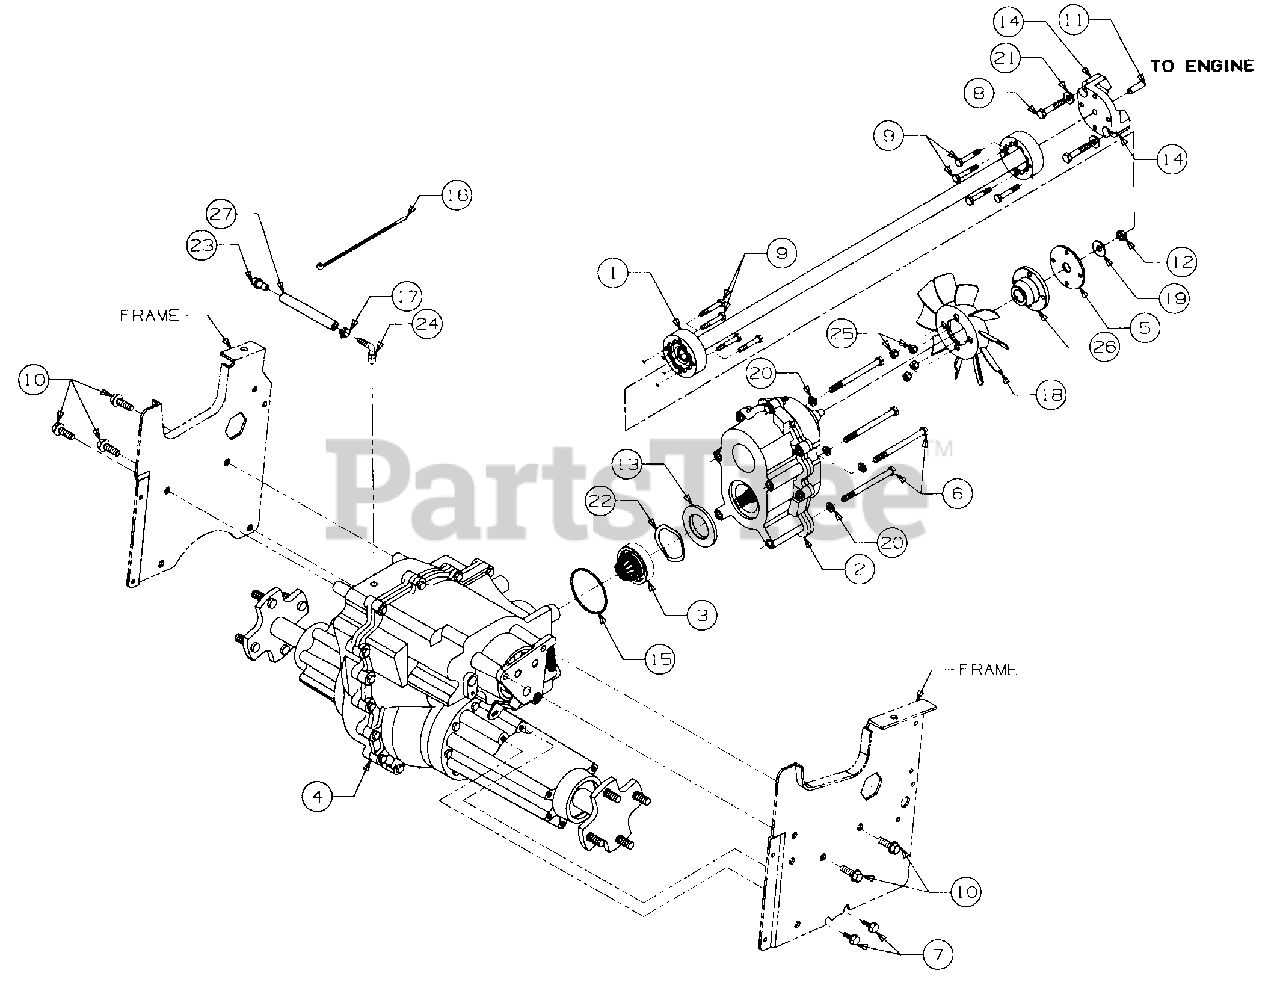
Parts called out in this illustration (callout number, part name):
1	Shaft Assy, Drive, 29.06 Lg
2	Clutch Assy
3	Pinion Assy, Input
4	Transmission Assy, 6-Speed
5	Plate, Drive Shaft Spacer
6	Screw, Hex Cap, 5/16-18 x 4.0 Lg GR5
7	Screw, Hex Wash Sf-Tapp 5/16-18 x .75 Lg
8	Screw, Hex Cap, 5/16-18 x .75 Lg GR5
9	Bolt, Hex Patch, 1/4-20 x 1.62 Lg GR5
10	Screw, Hex Wash Tapp 3/8-16 x 1.25 Lg
11	Pin, Locating
12	Nut, Hex Center Lock Jam, 3/8-24
13	Plate, Clutch Output Shim
14	Adapter, Drive Shaft
15	O-Ring, 2.75 x .103
16	Tie, Self-Clinch Cable
17	Clamp, Hose
18	Fan, 10 Blade Cooling
19	Washer, Bell, .380 x .88 x .062 Thk
20	Washer, Lock, 5/16
21	Washer, Flat, .312 x .750 x .119 Thk
22	Washer, Spring Wave, 1.96 x 2.44 x .06 Thk
24	Fitting, Elbow
25	Nut, Fan, 1/4-20
26	Adapter, Clutch
27	Line, Fuel, 7 in. Lg
